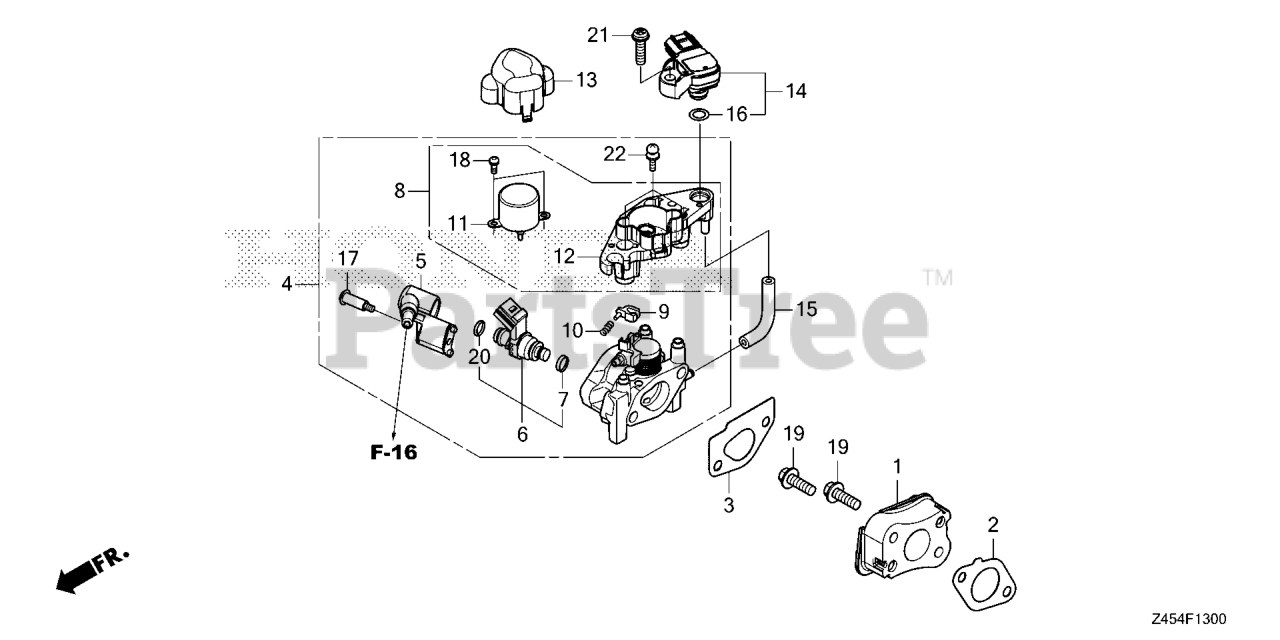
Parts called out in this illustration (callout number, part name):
1	INSULATOR COMP
2	GASKET, INSULATOR
3	GSKT, THROTTLE BODY
4	BODY ASSY., THROTTLE
5	JOINT, INJECTOR
6	INJECTOR ASSY., FUEL
7	RING, SEAL
8	MOTOR ASSY.
9	LEVER, LINK (CARBURETOR NO.)
10	SPRING, COMPRESSION COIL (CARBURETOR NO.)
11	MOTOR, THROTTLE CONTROL
12	BRKT, THROTTLE MOTOR
13	COVER, THROTTLE MOTOR
14	SENSOR ASSY., MAP
15	TUBE, MAP SENSOR
17	SCREW, SHOULDER
18	SCREW-WASHER (3X8)
19	BOLT, FLANGE (6X18) (NSHF)
20	O-RING (6.3X2.2)
21	SCREW-WASHER (5X20)
22	SCREW-WASHER (4X10)
